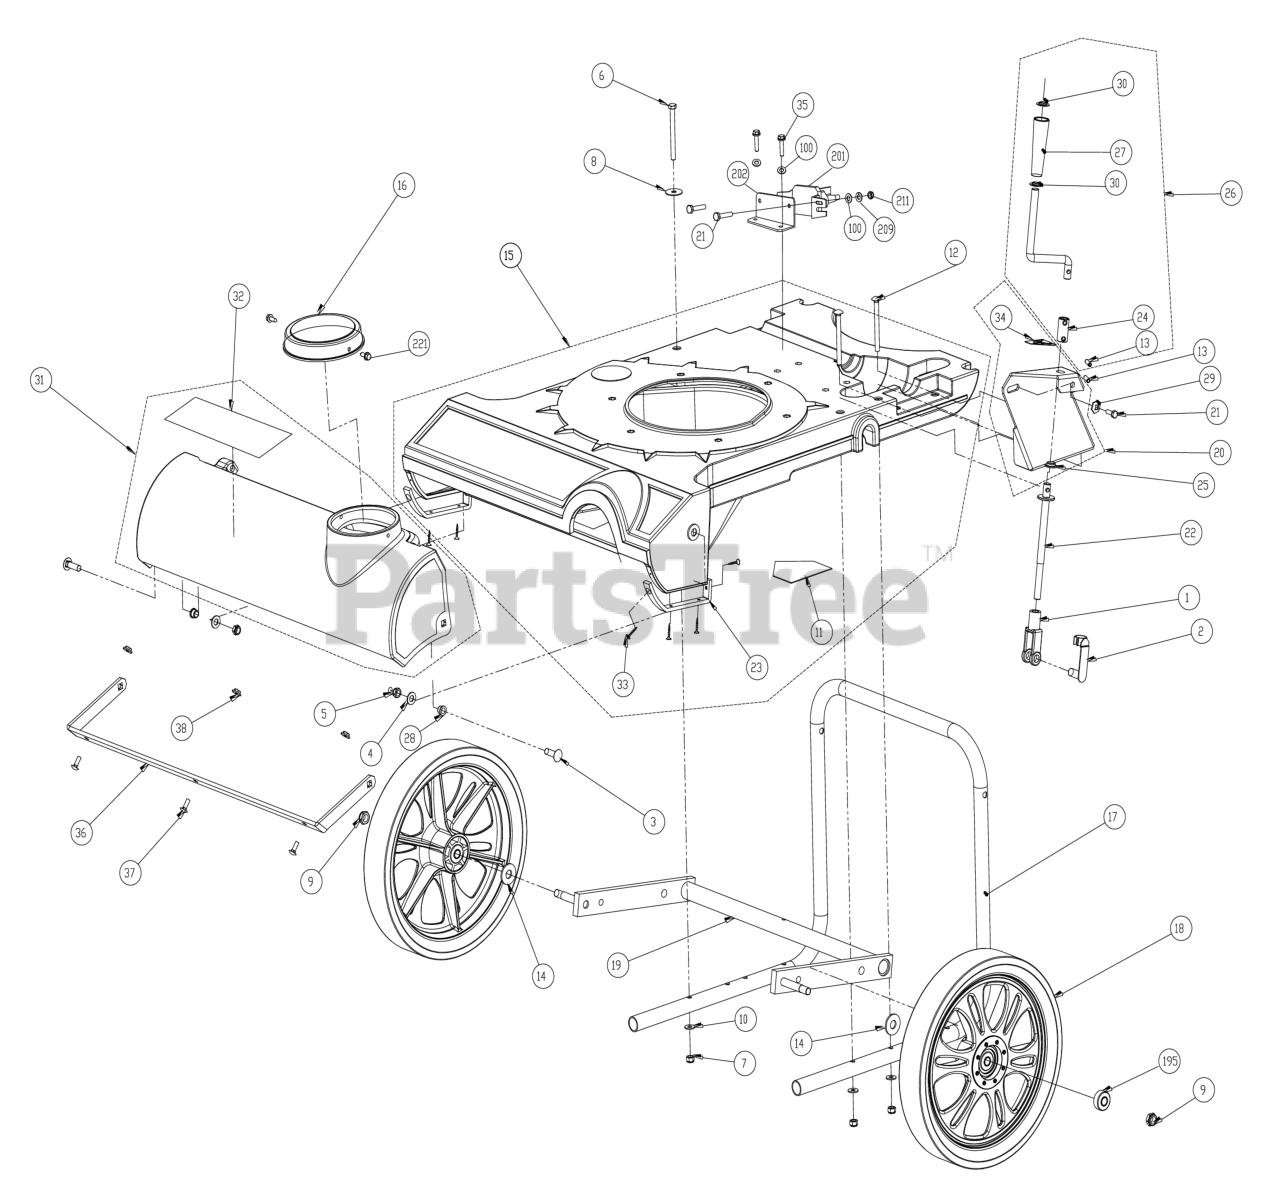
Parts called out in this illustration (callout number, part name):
1	YOKE 1/2"-20
2	PIN YOKE 1/2"
3	SCREWCAP BUTTON HEAD, 3/8-16 X 1 1/4" PL
4	WASHER 3/8"SAE 13/32"X13/16"X1/16"
5	NUT LOCK 3/8-16 LT WT THIN ZP
6	SCREWCAP 5/16"-18X3 1/2" HCS ZP
7	NUT LOCK 5/16"-18 HEX Z/P
8	WASHER FLAT FENDER 5/16
9	NUT LOCK 1/2"-13 NYLON INSERT
10	WASHER 1/4" FLAT Z/P
11	LABEL WARNING OPEI
12	BOLT CARRIAGE 5/16"-18 X 3 1/2" ZP
13	PIN ROLL 1/4" X 1"
14	WASHER 1/2" SAE Z/P
15	NOZZLE MV VAC ASSEMBLY
16	PLUG HOSE 5" VAC
17	HANDLE LOWER BRACE MV
18	WHEEL AND TIRE 14" SMOOTH
19	AXLE FRONT WA VAC
20	BRACKET HGT ADJ WA WA/LABEL MV VAC
21	SCREWCAP 1/4"-20X3/4" HCS ZP
22	LINK HGT ADJ SP VAC
23	BRACKET NOZZLE WEAR GUARD VAC
24	ROD CONNECT HGT ADJ
25	BUSHING 0.5 ID 0.625 OD X 0.25
26	ROD HANDLE CRANK ASSEMBLY
27	HANDLE CRANK
28	BUSHING 3/8 ID X 1/2 OD X 3/8
29	WASHER LOCK 1/4" TWISTED TOOTH
30	INTERNAL TOOTH WASHER BRASS
31	NOZZLE COVER MV VAC ASSY
32	LABEL BADGING MV
33	SCREW SHEETROCK 1" LONG
34	LABEL HGT ADJ MV VAC
35	SCREW SM 1/4"X3/4" TYPE A HX WF
36	BRACKET NOZZLE COVER REINFORCE
37	BOLT CARRIAGE 1/4" X 3/4"
38	NUT WHIZ 1/4"-20 WASH FACE
100	WASHER 1/4"SAE9/32"X5/8"X1/16"
195	BEARING 1/2 ID
201	SOLENOID ELECTRIC START
202	BRACKET SOLONOID MOUNT
209	WASHER LOCK 1/4" EXTERNAL TOOTH
211	NUT 1/4"-20 FIN HEX Z/P
221	SCREW PLASTITE 1/4-10 X 3/4 HWH ZP
